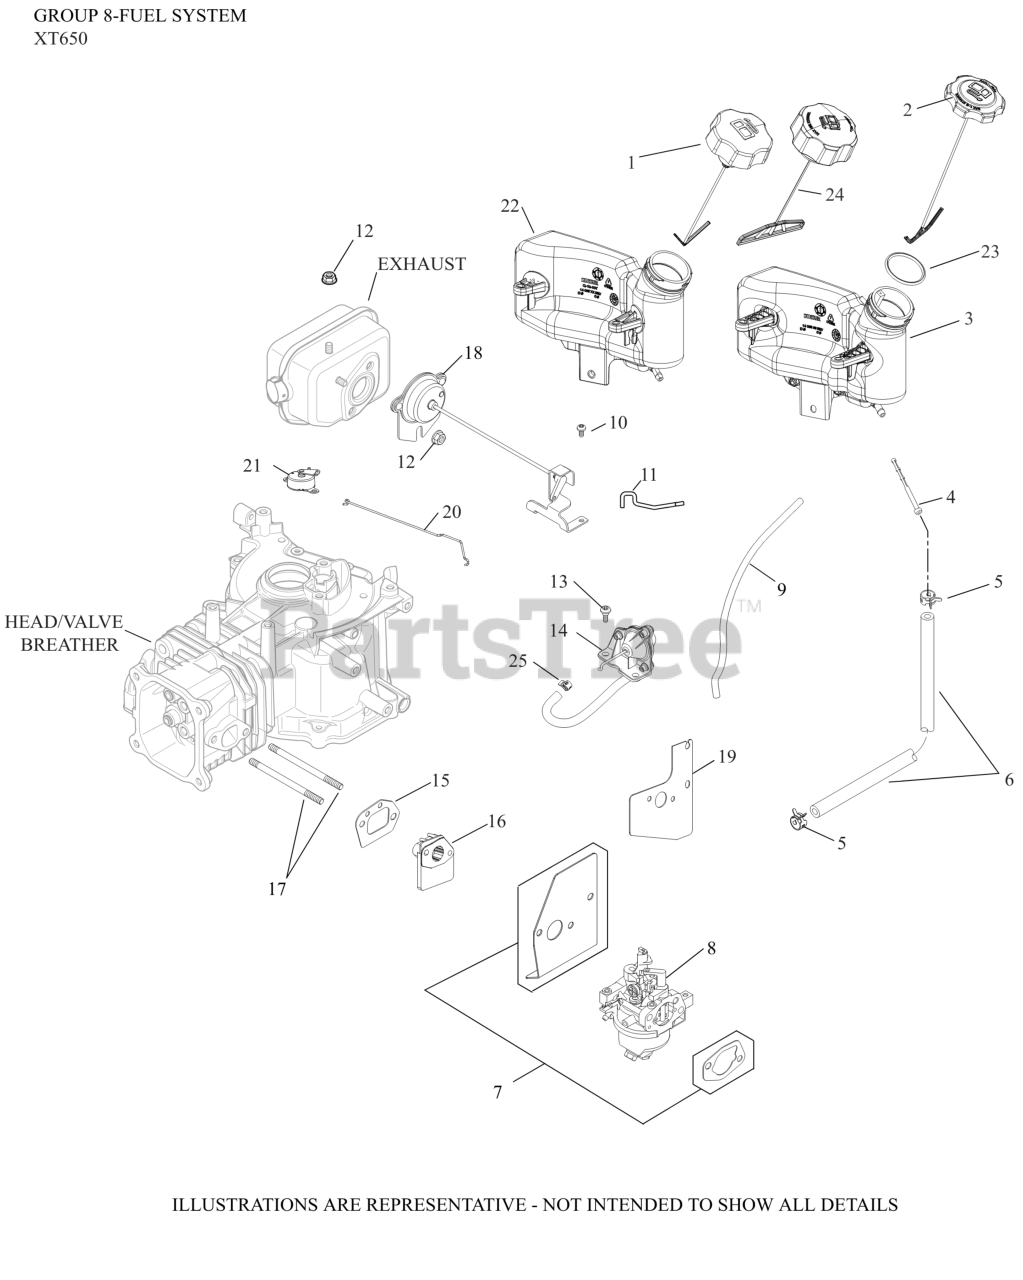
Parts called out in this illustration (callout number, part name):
2	CAP ASSEMBLY, FUEL
3	TANK, FUEL
4	FILTER, FUEL IN-NIPPLE
5	CLAMP, HOSE (NON-CALIF)(#1423710S)
6	HOSE, FUEL LOW-PERMEATION (CKY)
7	KIT, CARBURETOR HEAT SHIELD GASKET
8	KIT,CARB (HUAYI) 12MM A. C
9	HOSE, EVAPORATIVE 20"- (#24326143S)
15	GASKET, SPACER - USE 14 041 24-S
16	SPACER, CARBURETOR
17	STUD,M6X1.0X100.2MM
20	LINKAGE, AUTO CHOKE
21	ARM ASSY,AUTO CHOKE-USE 14 187 22-S
23	SEAL, FUEL CAP
NI	KIT, HIGH ALTITUDE (4,000-8000 FT)
